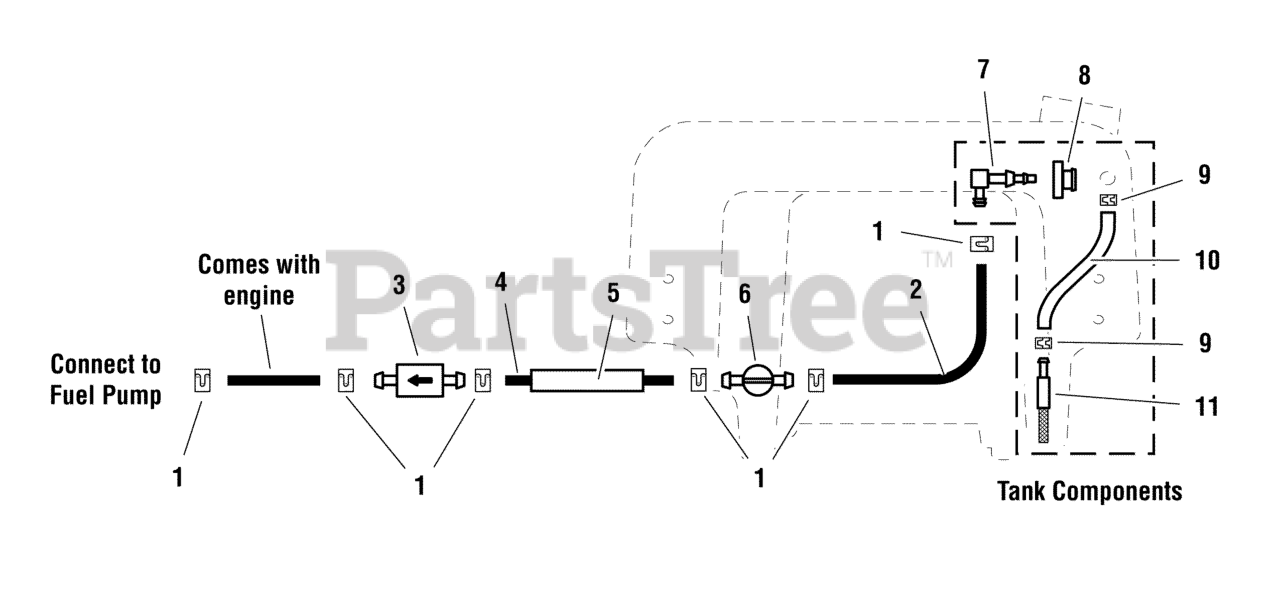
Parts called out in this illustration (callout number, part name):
1	CLAMP, Hose
2	1/4" Fuel Line, 5" Long
3	FUEL FILTER
4	1/4" Fuel Line, 35" Long
5	WIRE LOOM, 23"
6	VALVE, Fuel Shut-Off
7	ELBOW FITTING
8	BUSHING-FUEL TANK RED RUBBER
9	SEE HOSE ASSEMBLY
10	ASSM, FUEL HOSE, 20"
11	SEE HOSE ASSEMBLY
